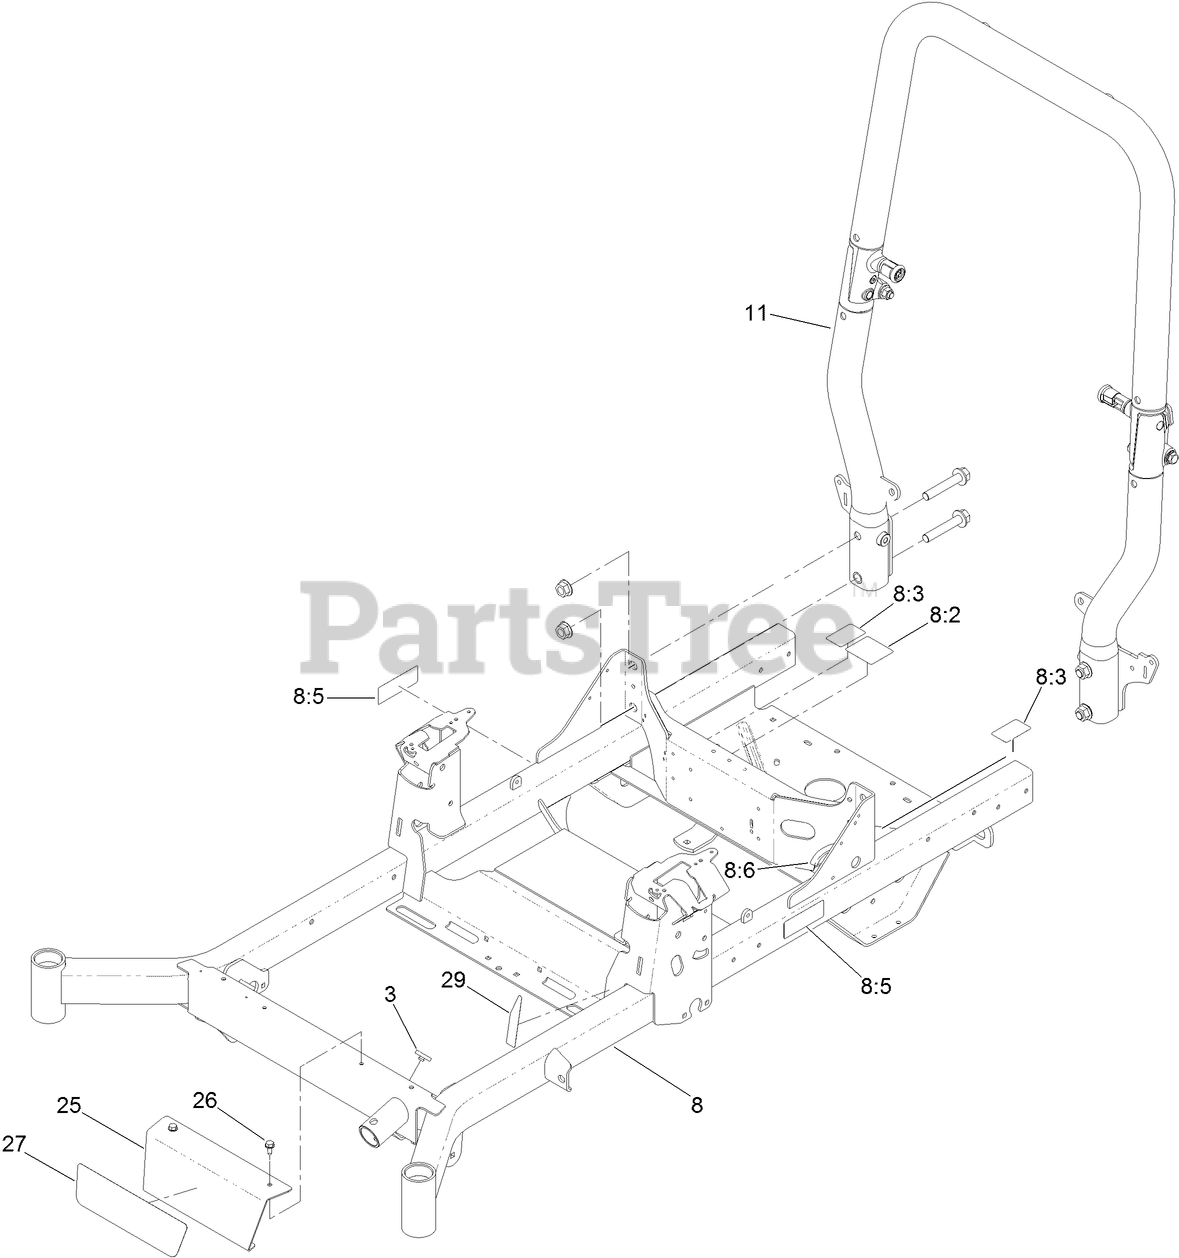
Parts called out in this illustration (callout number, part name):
3	BUMPER-PUSH-IN, RUBBER
8	FRAME-60, SUSPENSION
8:2	DECAL-ROUTING, BELT
8:3	DECAL-RELEASE, DRIVE
8:5	DECAL-WARNING
8:6	STRIP-SEAL
11	ROPS ASM
25	PLATE-FRONT
26	SCREW-HWHTF
27	DECAL-TITAN HD
29	DECAL-FILL, FUEL
